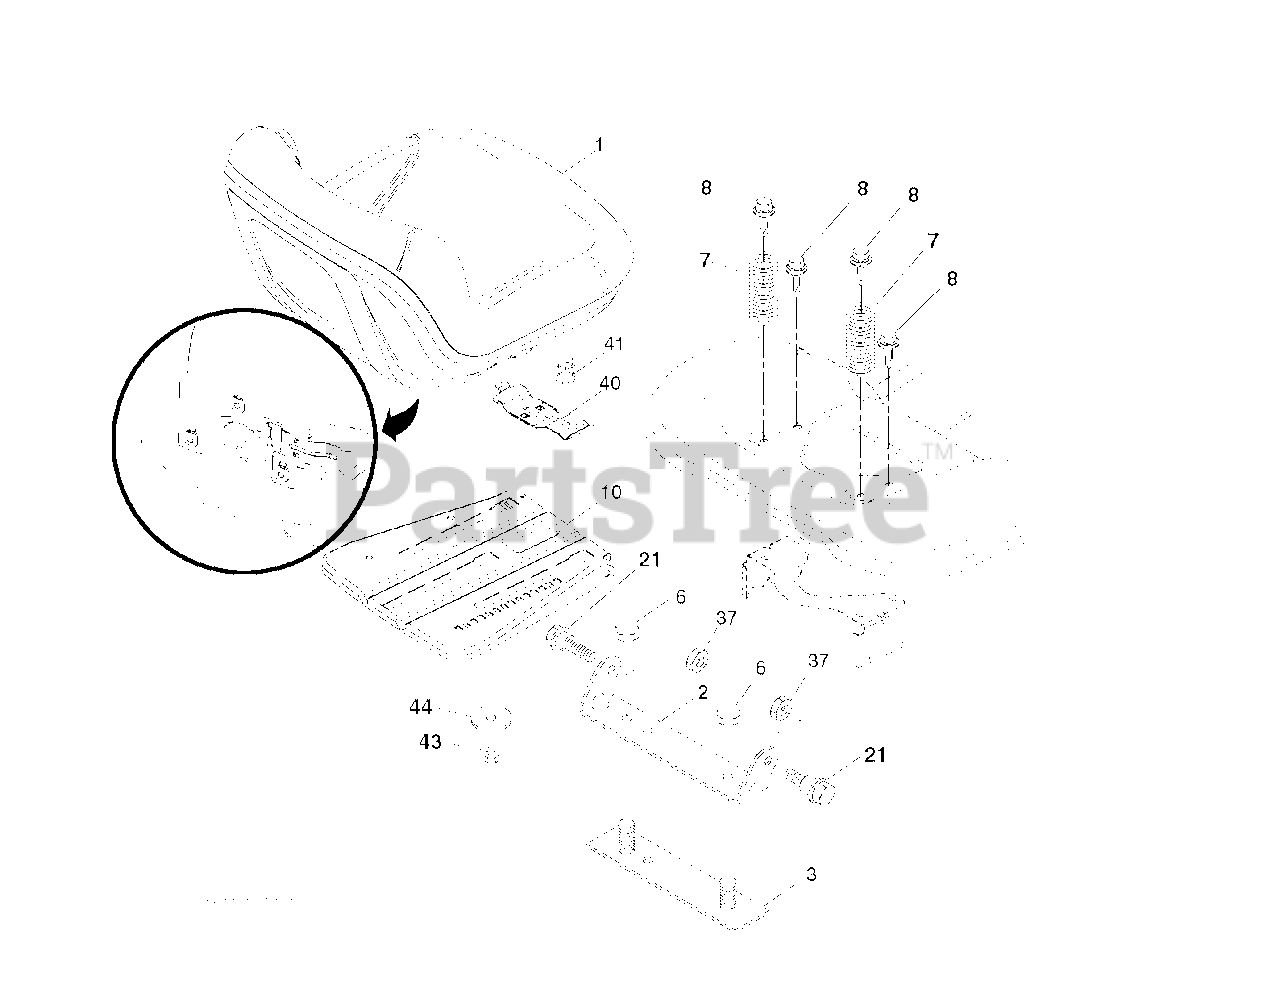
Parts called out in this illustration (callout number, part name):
1	SEAT.TG130.BLACK.NO/LOGO.
2	BRKT.PIVOT.FENDER
6	NUT
7	SPRING COMPRESSION
8	BOLT, 5/16-18 X 1 3/4
10	PAN.ASM.SEAT.3PT
21	BOLT.SHOULDER.5/16-18
37	NUT.71038.31-18.HEX.NYLOCK
40	HANDLE.SLIDE.SEAT.TEX.BLACK
41	SPRING.LATCH.SEAT.TEX
44	WASHER 13/32 X 2-3/8 X 12GA
